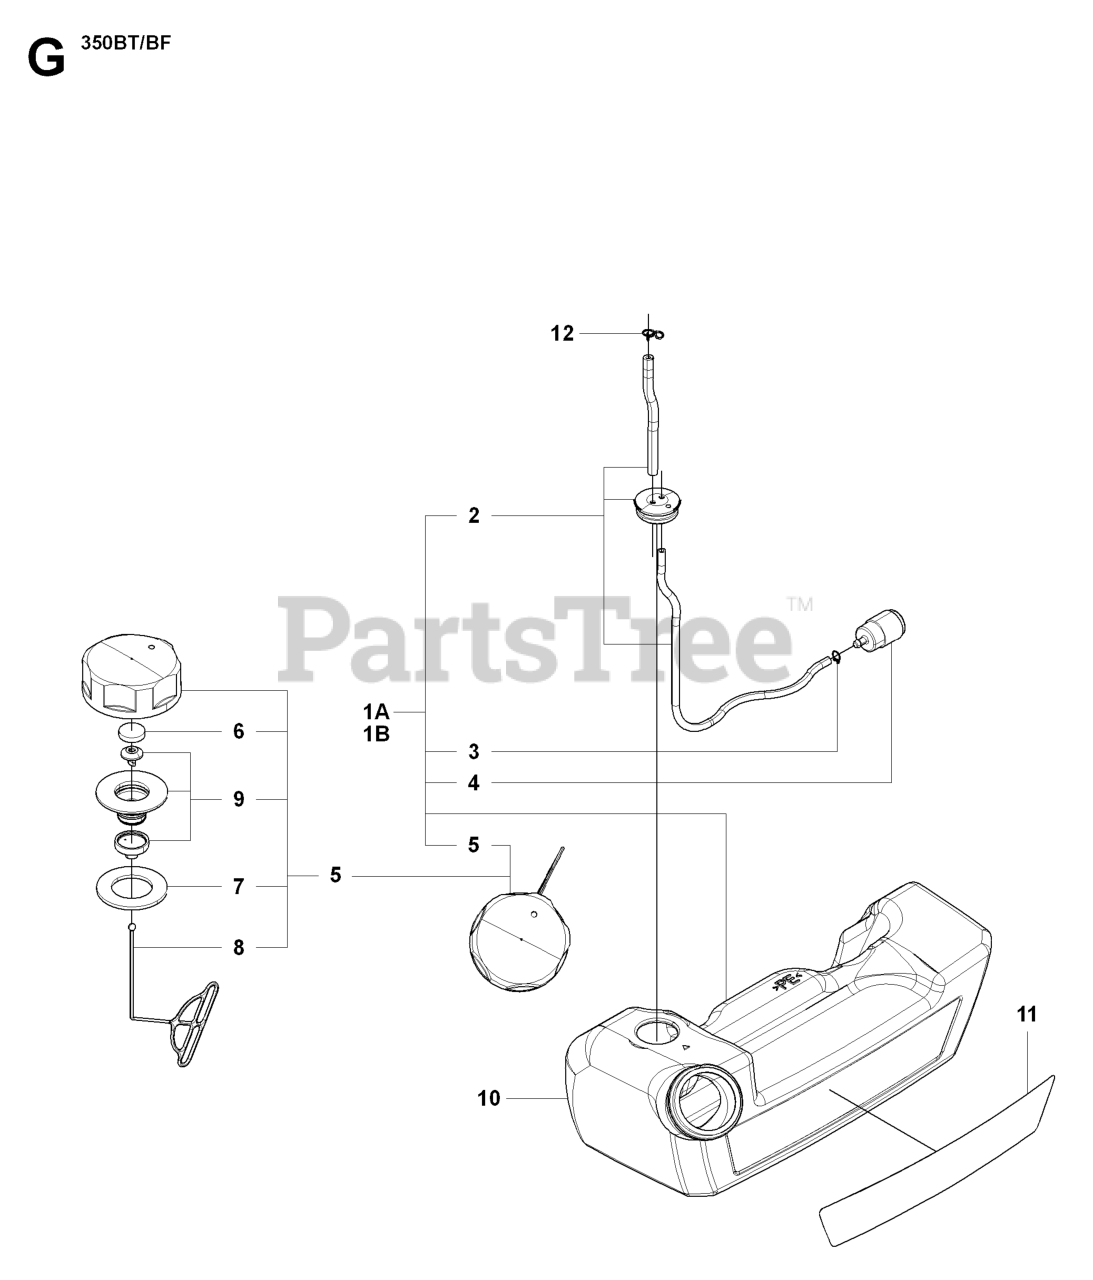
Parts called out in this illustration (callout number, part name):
1A	TANK ASSY
1B	FUEL TANK ASSY
2	PIPE C
4	FILTER ASSY
5	ASSY FUEL CAP
